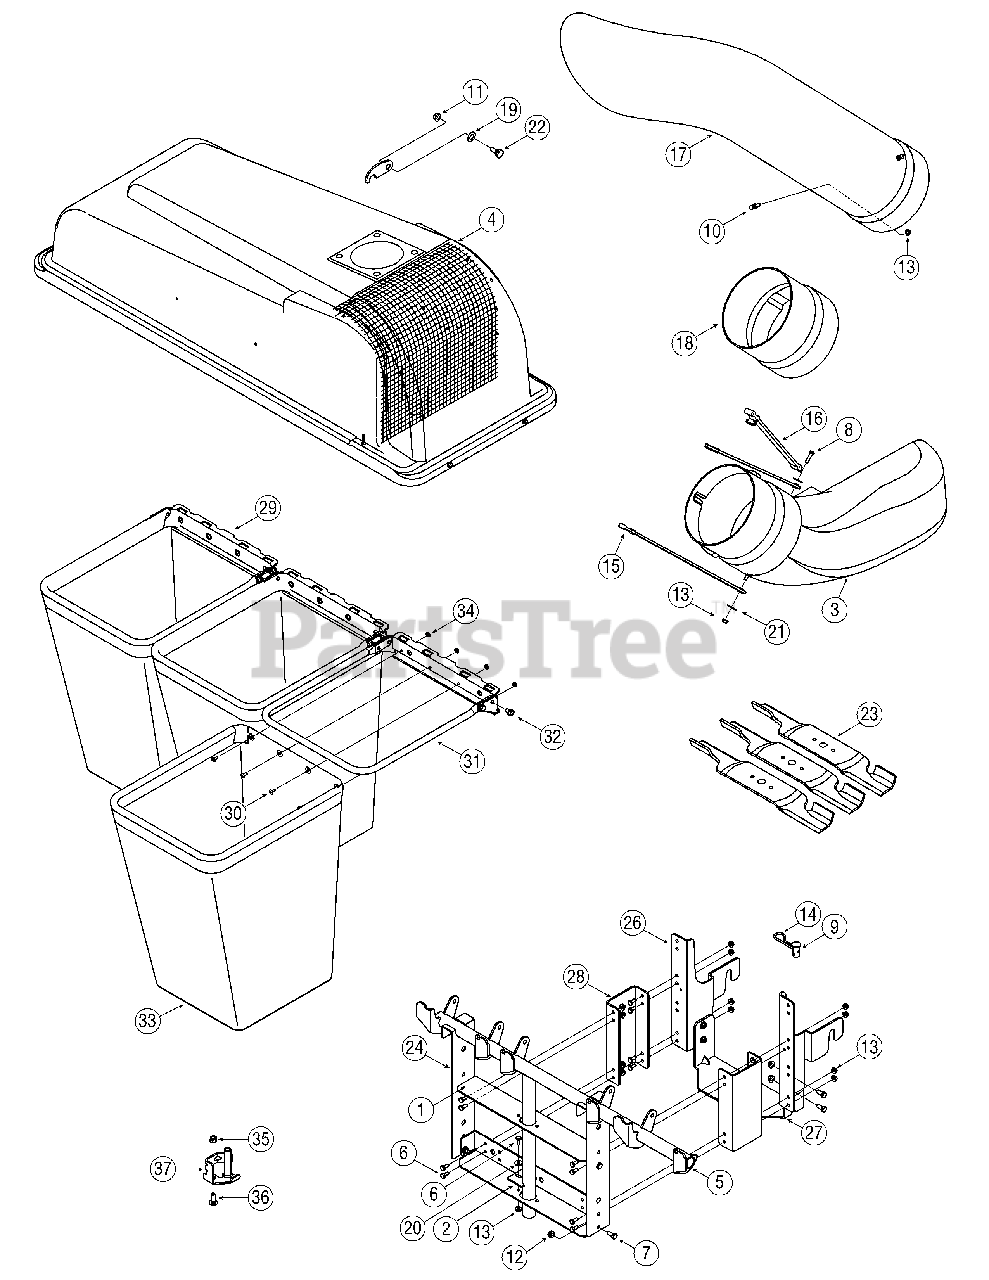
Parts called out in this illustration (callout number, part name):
1	Catcher Support Bracket
3	Elbow Chute Assembly
4	Grass Catcher Cover Assembly
5	Grass Catcher Support Assembly
6	Hex Cap Screw, 1/4-20 x .62
7	Hex Cap Screw, 5/16-18 x .75
8	Hex Cap Screw, 1/4-20 x 1.00
9	Clevis Pin
10	Grass Catcher Pin, 1/4-20
11	Hex Flange Lock Nut, 3/8-16
12	Hex Flange Lock Nut, 5/16-18
13	Hex Flange Lock Nut, 1/4-20
14	Internal Cotter Pin, .148 x 3
15	Chute Strap, 11.65
16	Retainer Strap Assembly
17	Chute Tube
18	Extension Tube
19	Belleville Washer
20	Bell Washer, .265 x .75 x .062
21	Flat Washer .265 x 1.0 x .030
22	Shoulder Screw, .50 x .27, 3/8-16
23	High Lift Blades 18.50"
30	Screw, #10-24 x .5
33	Grassbag
34	Hex Sems Nut, #10-24
35	Hex Lock Nut, 3/8-16
36	Carriage Bolt, 3/8-16: 1.00
